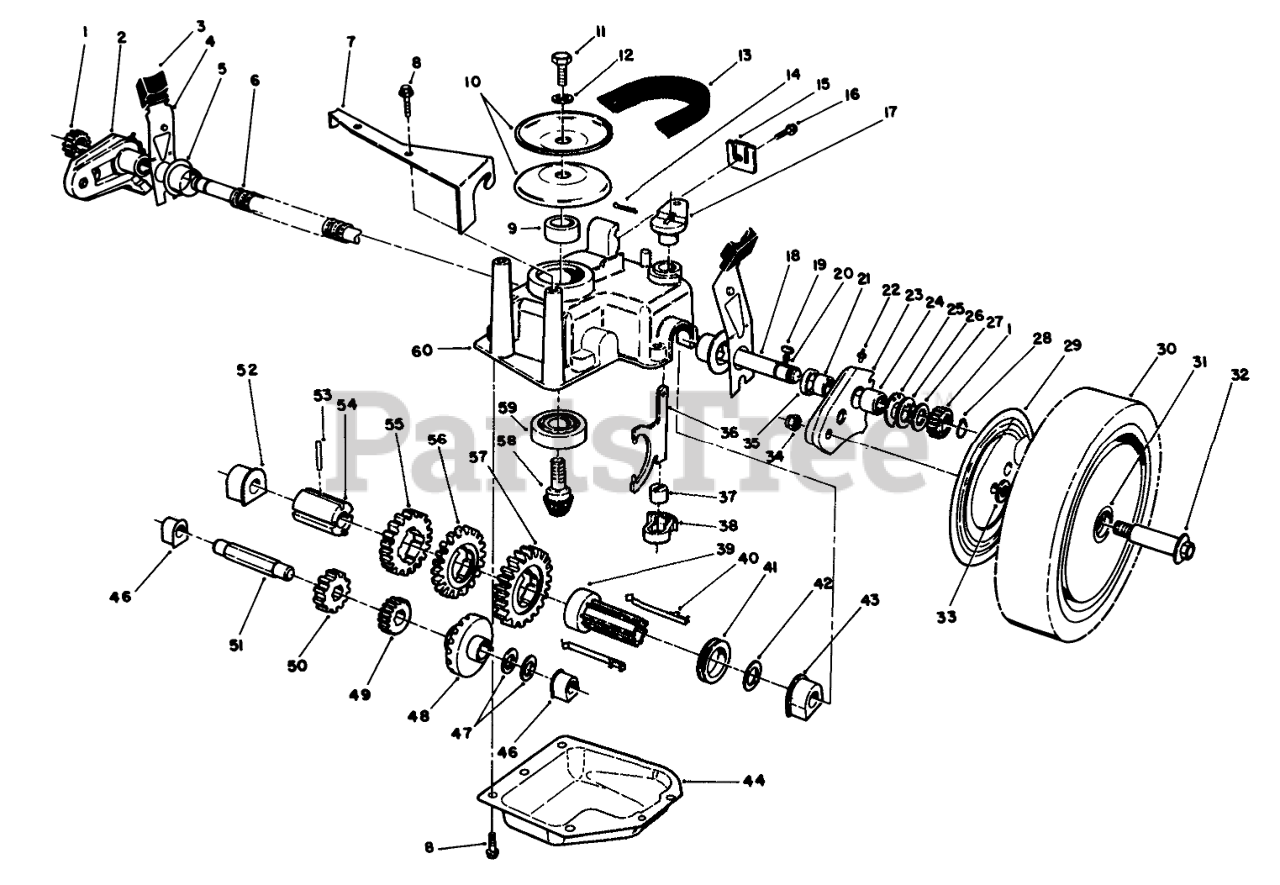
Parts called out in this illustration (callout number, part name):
1	GEAR-PINION
2	Pivot Arm Assembly-R.H. (Incl. Ref. #21, 22, 24 & 35)
3	KNOB-ARM
4	SPRING ARM ASM SP
5	CAP-END
6	CONDUIT-CONVOLUTED, SPLIT
7	Bracket-Guide
8	SCREW-HWHTF
9	SPACER
10	Pulley Half
11	NUT-HEX
12	WASHER-FLAT
13	V-BELT E
14	PIN-COTTER
15	Cable Clamp
16	SCREW-HWHTF
17	SHIFT LEVER
18	Output Shaft
19	KEY RECTANGULAR
20	SPRING-COMPRESSION
21	BUSHING
22	FITTING-GREASE
23	Pivot Arm Assembly-L.H. (Incl. Ref. #21, 22, 24 & 35)
24	BEARING-ROLLER
25	INNER THRUST WASHER
26	WASHER-THRUST, OUTER
27	WASHER-THRUST, OUTER
28	RING-RETAINING
29	WHEEL COVER
30	Wheel-Tire & Gear Assy. (Incl. Ref. #31)
31	BUSHING
32	WHEEL BOLT
33	WASHER
34	Nut
35	SEAL-OIL
36	YOKE-SHIFT
37	BUSHING-YOKE
38	RETAINER-FORK, SHIFT
39	Sleeve-Shift Key
40	Key Shift
41	SHIFT COLLAR
42	WASHER-PLAIN
43	BUSHING-OUTPUT
44	Cover-Gearcase
46	BUSHING
47	WASHER-THRUST
48	Gear-Bevel
49	PINION-20T
50	PINION-25T
51	SHAFT-INTERMEDIATE
52	BUSHING
53	PIN-SPRING
54	SLEEVE-GEAR
55	GEAR-39T
56	GEAR-44T
57	GEAR-49T
58	Gear-Pinion
59	BEARING-BALL
60	CASE-GEAR, UPPER
